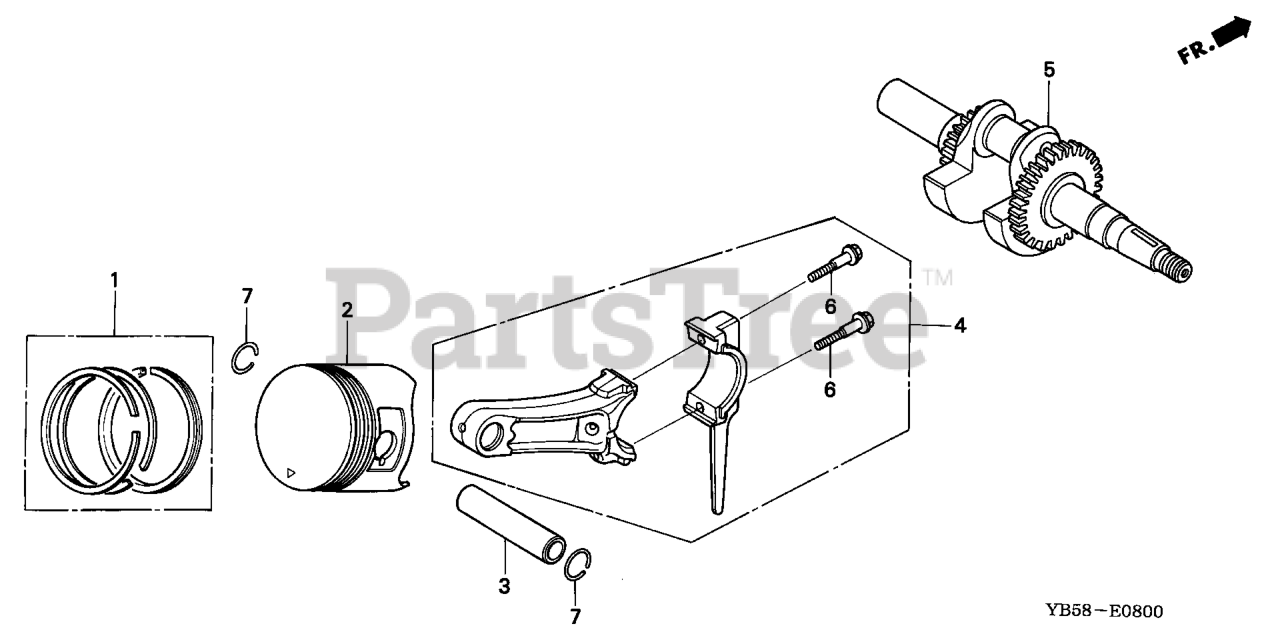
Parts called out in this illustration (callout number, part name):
1	RING SET, PISTON (STD) (TEIKOKU)
1	RING SET, PISTON (STD.) (TEIKOKU)
1	RING SET, PISTON (STD.) (NIPPON)
1	RING SET, PISTON (OVER SIZE) (0.25) (TEIKOKU) Use up to Engine SN 4733210.
1	RING SET, PISTON (OS 0.25) Use from Engine SN 5495900 to 7603338.
1	RING SET, PISTON (OS 0.25) Use from Engine SN 7603339.
1	RING SET, PISTON (0.25) (NIPPON) Use up to Engine SN 1314912.
1	RING SET, PISTON (OVER SIZE) (0.50) (TEIKOKU) Use up to Engine SN 4733210.
1	RING SET, PISTON (OS 0.50) Use from Engine SN 5495900 to 7603338.
1	RING SET, PISTON (OS 0.50) Use from Engine SN 7603339.
1	RING SET, PISTON (0.50) (NIPPON) Use up to Engine SN 1314912.
1	RING SET, PISTON (OVER SIZE) (0.75) (TEIKOKU) Use up to Engine SN 4733210.
1	RING SET, PISTON (0.75) (NIPPON) (NOT AVAILABLE)
1	RING SET, PISTON (0.75) Use from Engine SN 5495900 to 7603338.
1	RING SET, PISTON (0.75) (TEIKOKU) Use up to Engine SN 1314912.
1	RING SET, PISTON (0.75) (NIPPON) Use up to Engine SN 1314912.
2	PISTON (STD)
2	PISTON (OS 0.25) Use from Engine SN 7603339.
2	PISTON (0.50) Use up to Engine SN 1314912.
2	PISTON (0.75) Use up to Engine SN 1314912.
3	PIN, PISTON
4	ROD ASSY., CONNECTING
4	ROD ASSY., CONNECTING (0.25 LOWER SIZE) (NOT AVAILABLE)
5	CRANKSHAFT (WB-TYPE)
6	BOLT, CONNECTING ROD
7	CLIP, PISTON PIN (18MM)
